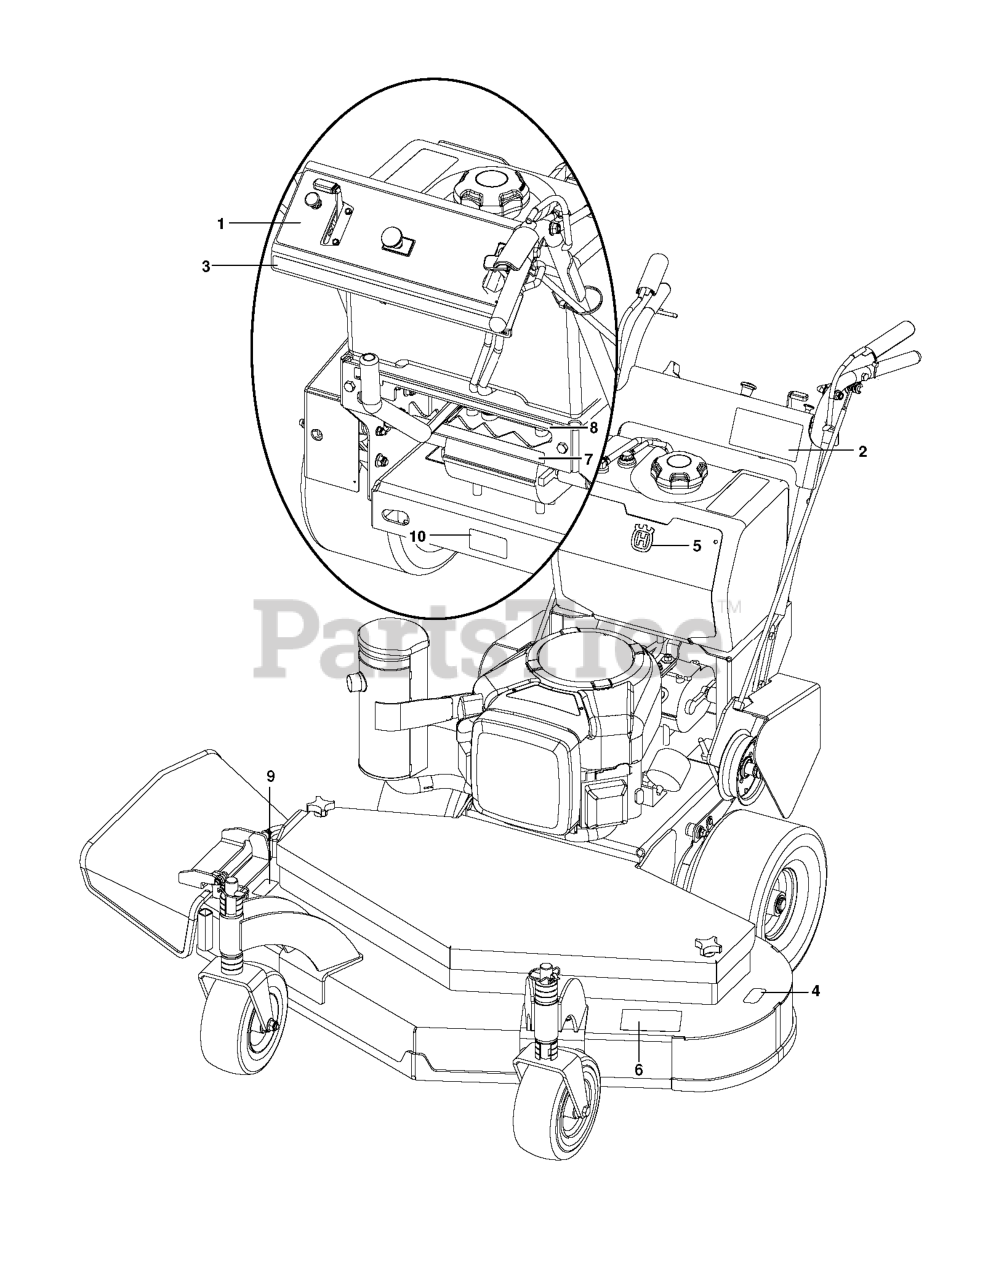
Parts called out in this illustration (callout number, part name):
1	DECAL DECAL, CONSOLE HUSQ GW
2	DECAL DECAL, CONSOLE W436
3	DECAL DECAL, CONTROL STEERING
4	DECAL DECAL, DECK 36" HUSQ
5	DECAL DECAL, HUSQVARNA CROWN 5
6	DECAL DECAL, SAFETY - MOWER DE
7	DECAL DECAL, SHIFT DISENGAGE H
8	DECAL DECAL, SPD INDICATOR HUS
9	DECAL DECAL, SAFETY - DECK GUA
10	DECAL DECAL, SAFETY - GUARDING
